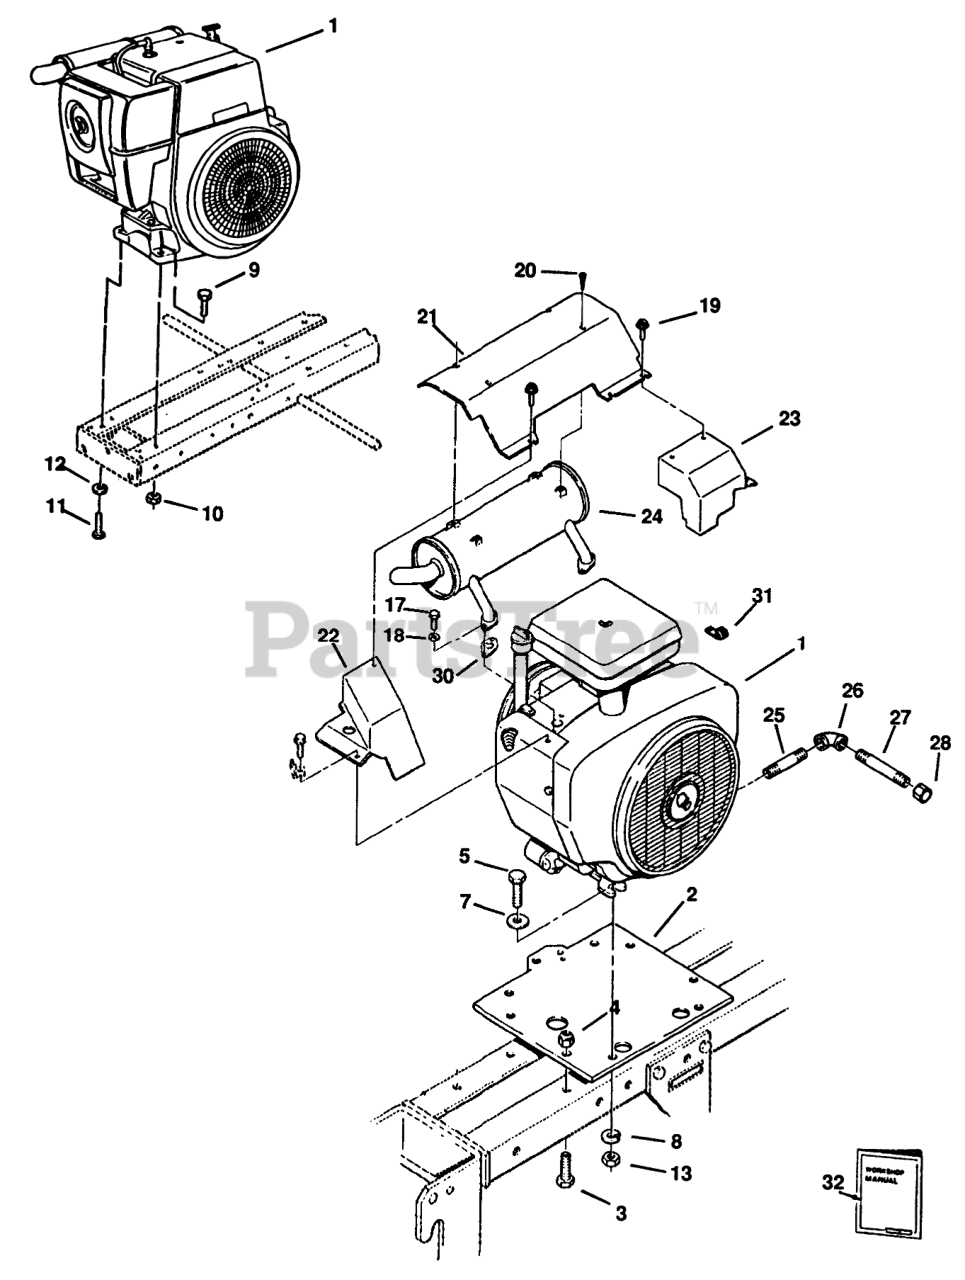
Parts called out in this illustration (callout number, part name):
1	Engine 10HP Kohler M-10-S Spec 461521 (s/n 1919902923 up)-310
2	PLATE-ENGINE *B
4	E.S. Nut 3/8-16
26	ELBOW 3/8 90 DEG
27	PIPE-NIPPLE 3/8 X 4"
31	J-CLIP
32	Magnum Kohler Service Repair Manual
